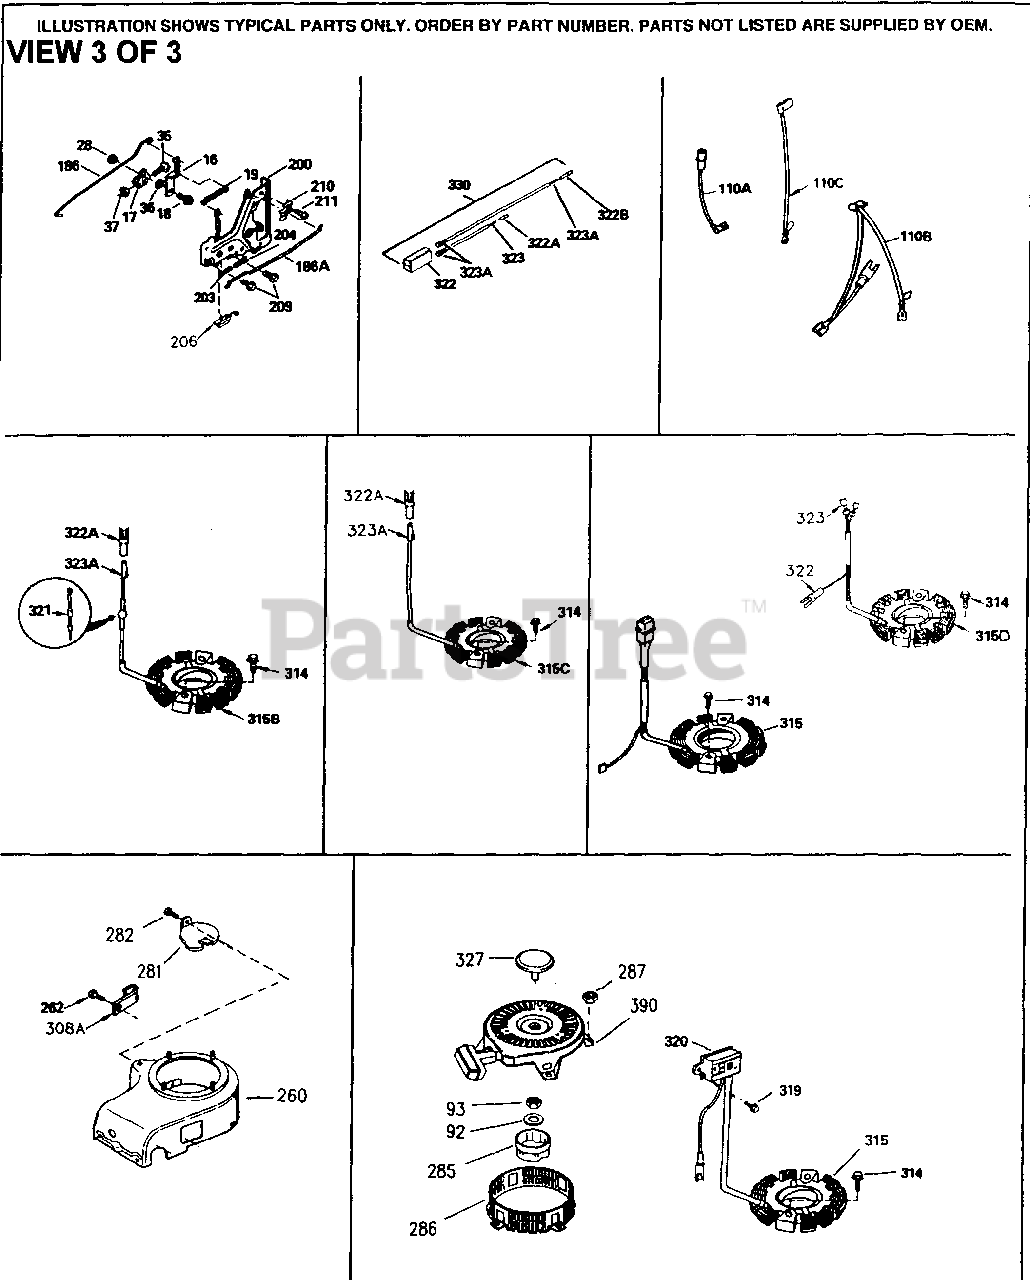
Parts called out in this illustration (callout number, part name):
16	Governor Lever (Incl. 212A)
17	Governor Lever Clamp
18	Screw, 8-32 x 5/16"
19	Extension Spring
28	Lock Nut, 8-32
35	Screw, 10-32 x 3/4"
36	Lock Washer #8
37	Lock Nut, 10-32
92	Lock Washer
93	Flywheel Nut
186	Governor Link
200	Control Bracket (Incl. 203 & 204)
203	Compression Spring
204	Screw, 6-32 x 21/32"
209	Screw, 10-32 x 7/16"
210	Conduit Clip
211	Screw, 10-32 x 3/8"
260	Blower Housing
262	Screw, T-40, 5/16-24 x 21/32"
286	Screen Cup
308A	Fill Tube Clip
314	Screw, 1/4-20 x 3/4"
315	Alternator Coil (3/5 Split) Incl. 321 -323
322	Connector Body
323	Terminal
370B	Decal - Important Lubrication - SAE 3
370C	Caution Decal
